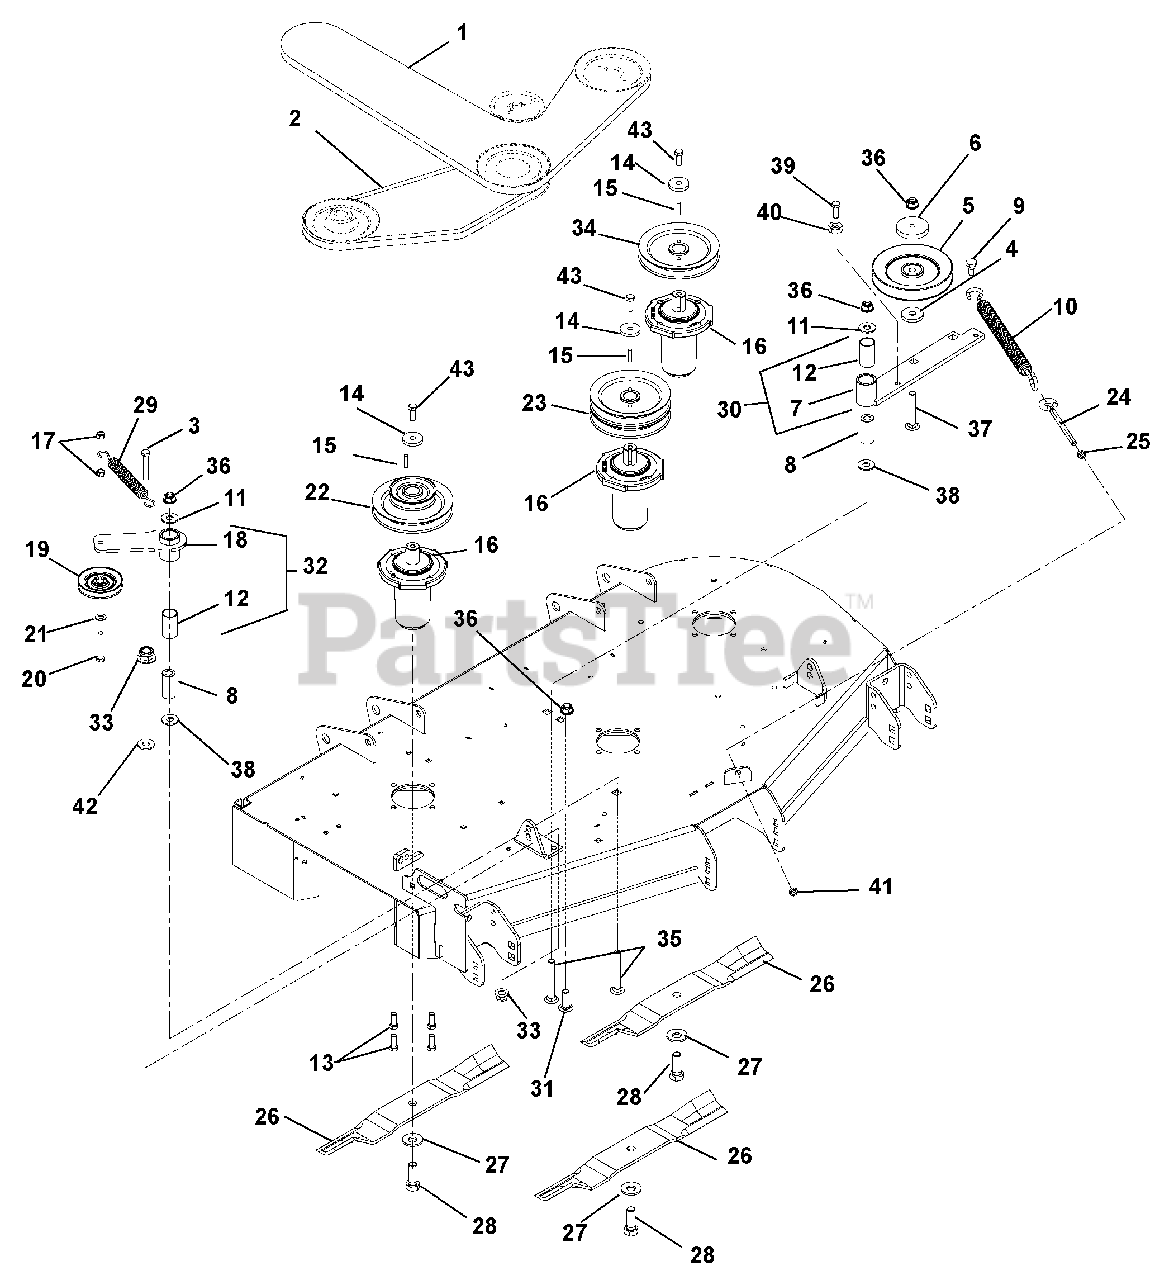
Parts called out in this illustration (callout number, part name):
1	HEX BELT, BB-WRAPPED
2	V-BELT, B-COGGED
3	@BLT-HEX .38-16X3.00 GR5 YWZC
4	BSHG, SPCR .502X.997X.50 PM
5	SHV, .50"ID X 6.00"OD V-IDLER
6	CAP, IDLER BEARING SEALING
7	WMT, IDLER ARM
8	BSHG, SPCR .502X.997X2.03 PM
9	BLT,SHLDR EP .38-16X.30 HEX YZ
10	SPRING, EXTENSION
11	@WSHR-FL-STL.563X1.38X.109YWZC
12	BSHG, 1.00 X 1.125 X 1.937
13	BLT-HEX .38-16X1.0 GR8 YZ EP30
14	RETAINER, SHEAVE
15	KEY, SQ .25X.25X1.00 RC 40-50
16	ASM, MAINT FREE SPINDLE
17	@NUT-LK-CTR .38-16 YWZC
18	WMT, IDLER ARM
19	IDLER, V-5.00"
20	@BLT-HEX .38-16X2.25 GR5 YWZC
21	@WSHR-FL-STL.406X.812X.065 YWZ
22	PULLEY, DBL-1"IDX5.75"&3.50"OD
23	PULLEY, DOUBLE-1"ID X 5.75"OD
24	BOLT, .38-16X4.50 .62 DIA EYE
25	NUT-HEX-JAM .375-16 YWZC
26	BLADE, 16.19" MOWER (HI-LIFT)
27	WSHR-BLVL .669X1.535X.138
28	BLT-HEX .62-18X1.75 GR8 YWZC
29	SPRING, EXTENSION
30	ASM, IDLER PIVOT ARM (PTO)
31	BLT-RDHDSHSQNKFT.50-13X1.50 G5
32	ASM, IDLER ARM (DECK)
33	@NUT-SPNLK-FLG .375-16 YWZC
34	PULLEY, V-1" ID X 5.75" OD
35	@BLT-RDHDSQNK .50-13X3.50 G5YZ
36	@NUT-LK-NYL-FLG .50-13 YWZC
37	@BLT-RDHDSQNK .50-13X3.00 G5YZ
38	WSHR-FLT .640X1.75X.250
39	@BLT-HEX .38-16X2.75 GR5 YWZC
40	@NUT-HEX .38-16 YWZC
41	@NUT-LK-CTR-JAM .375-16 YWZC
42	WSHR-FL-STL .406X1.375X.135 YZ
43	BLT-HEX .38-16X2.75 GR8 YWZC
